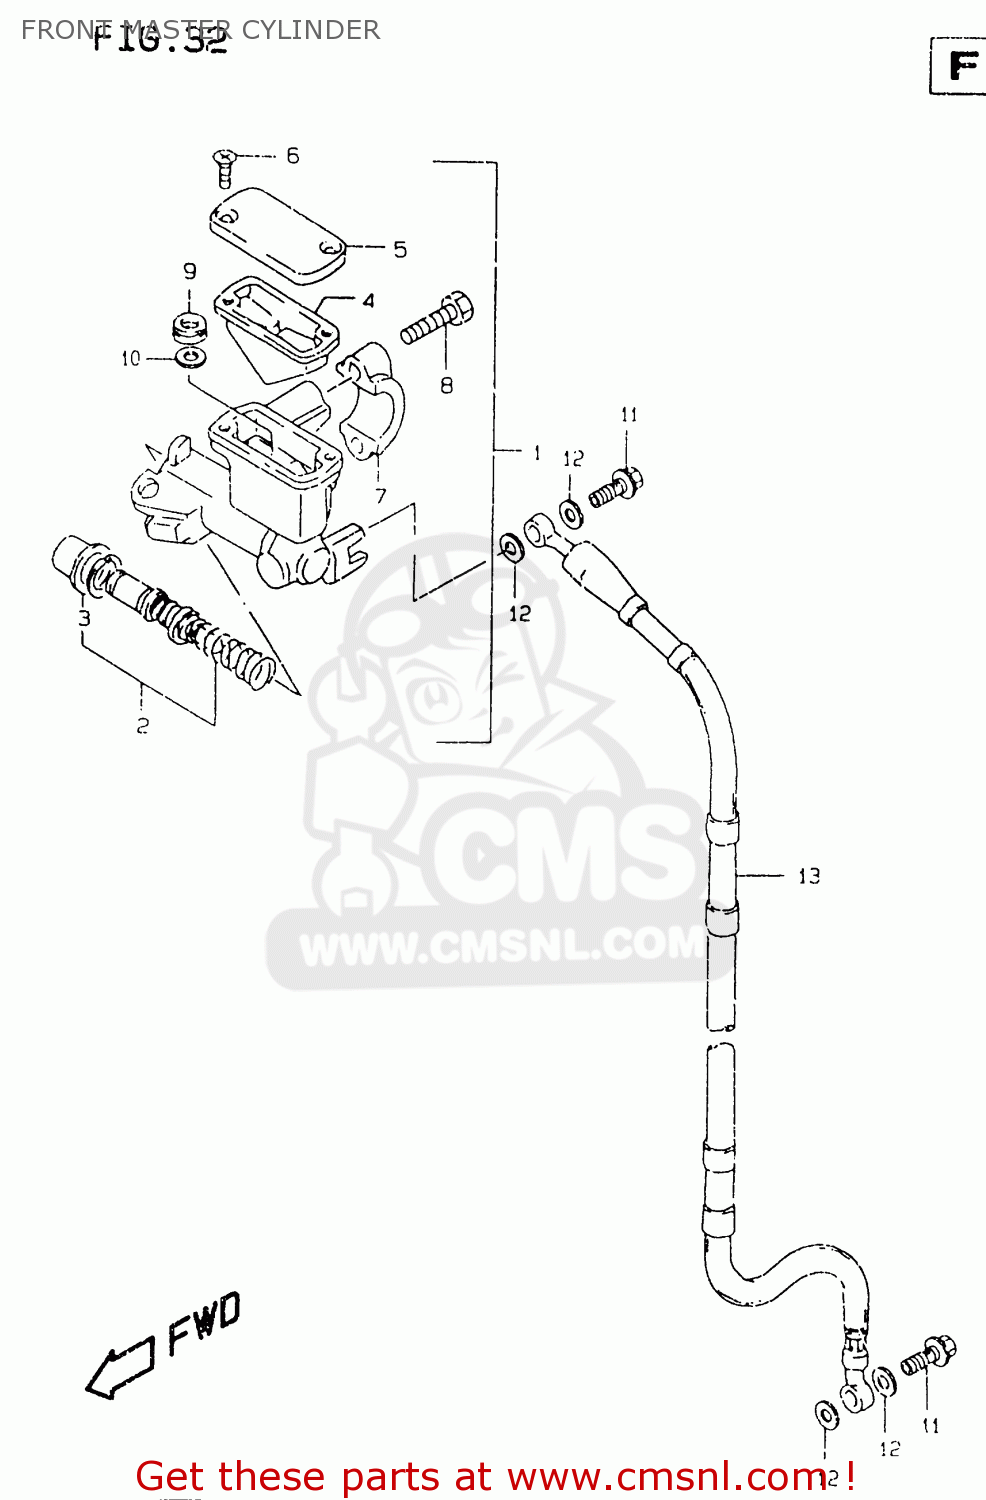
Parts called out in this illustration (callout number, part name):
1	CYLINDER ASSY,FR MASTER
2	PISTON & CUP SET
3	BOOT
4	DIAPHRAGM
5	CAP
6	SCREW
7	HOLDER
8	BOLT
9	SEPARATOR
10	RING
11	BOLT UNION
12	WASHER(10X15X1.5)
13	HOSE COMP,FRONT BRAKE
